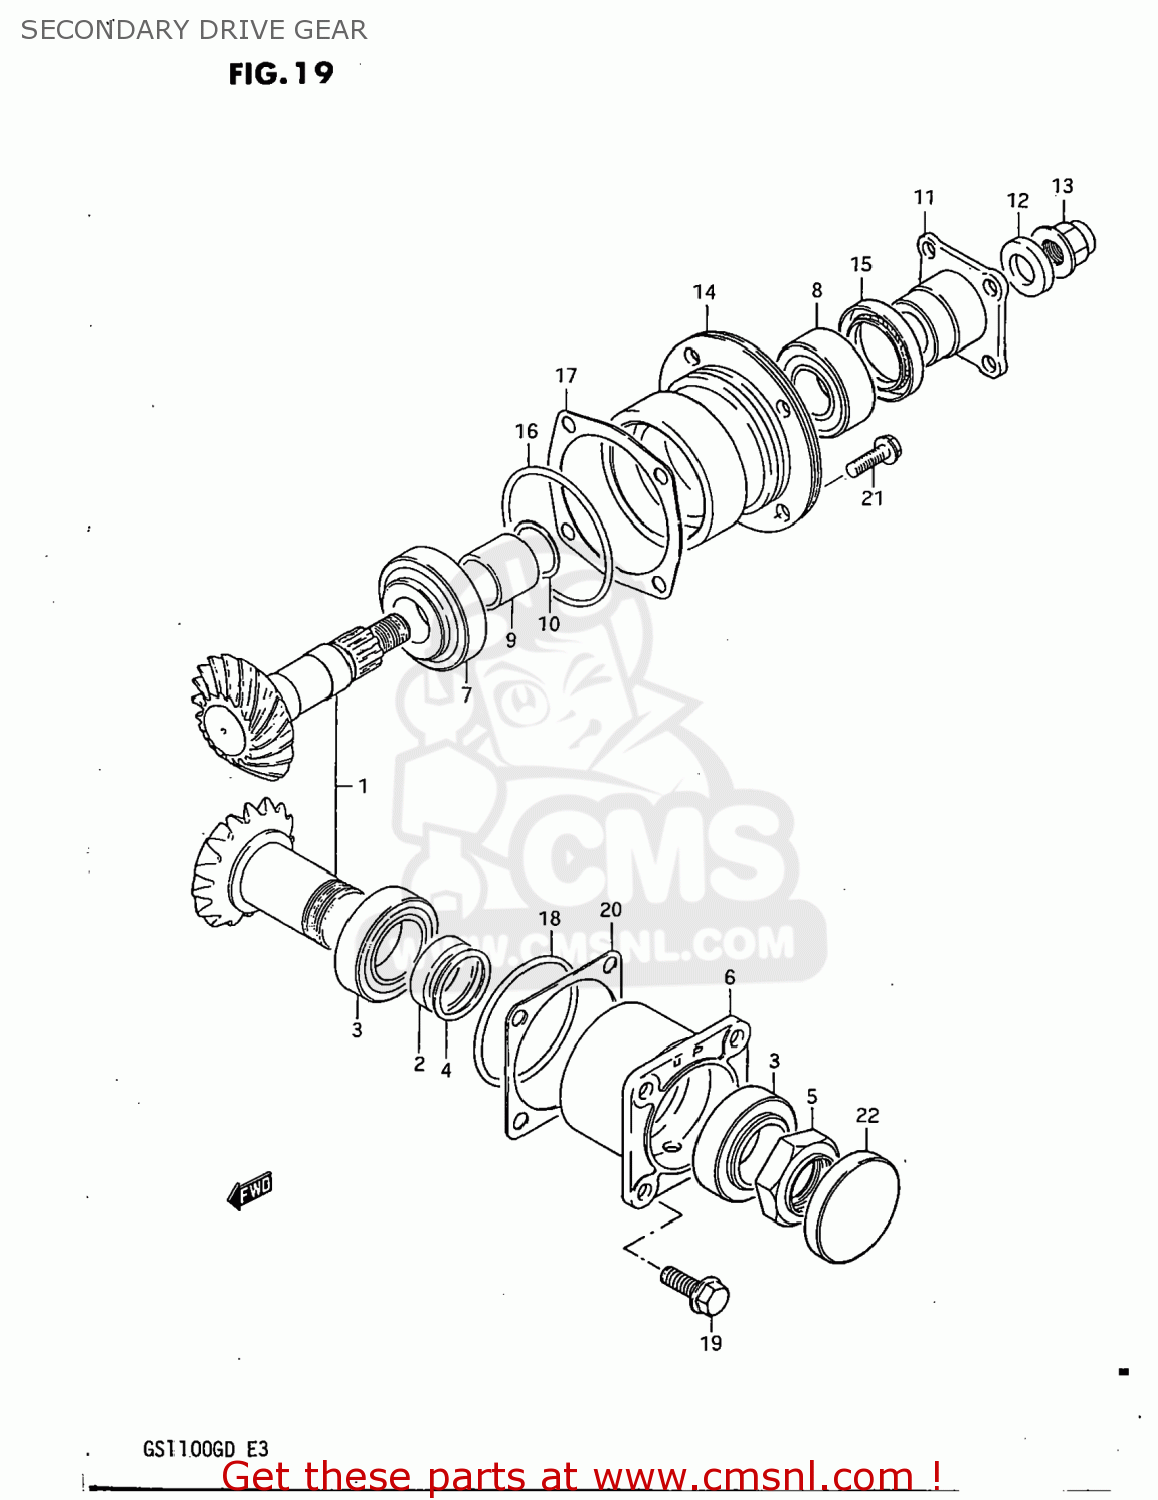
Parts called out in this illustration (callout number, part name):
1	SECONDARY GEAR SET
2	SPACER (32.4X38X12.5)
3	BEARING(32X58X17)
4	SHIM(32X38X2)
5	NUT
6	HOUSING,SECONDARY DRIVE
7	TAPER,ROLLER BEARING
8	BEARING
9	SPACER (25.2X30X40)
10	SHIM (25X30X2
11	FLANGE,UNIVERSAL JOINT
12	WASHER(14X29X4)
13	NUT
14	HOUSING,SECONDARY DRIVE
15	SEAL,OIL(35X52X9)
16	O RING(D:3.1,ID:69.4)
17	SHIM,DRIVEN GEAR HOUSING
18	O RING(D:2.4,ID:62.6)
19	BOLT
20	SHIM,SECONDARY DRIVE
21	BOLT
22	PLUG
